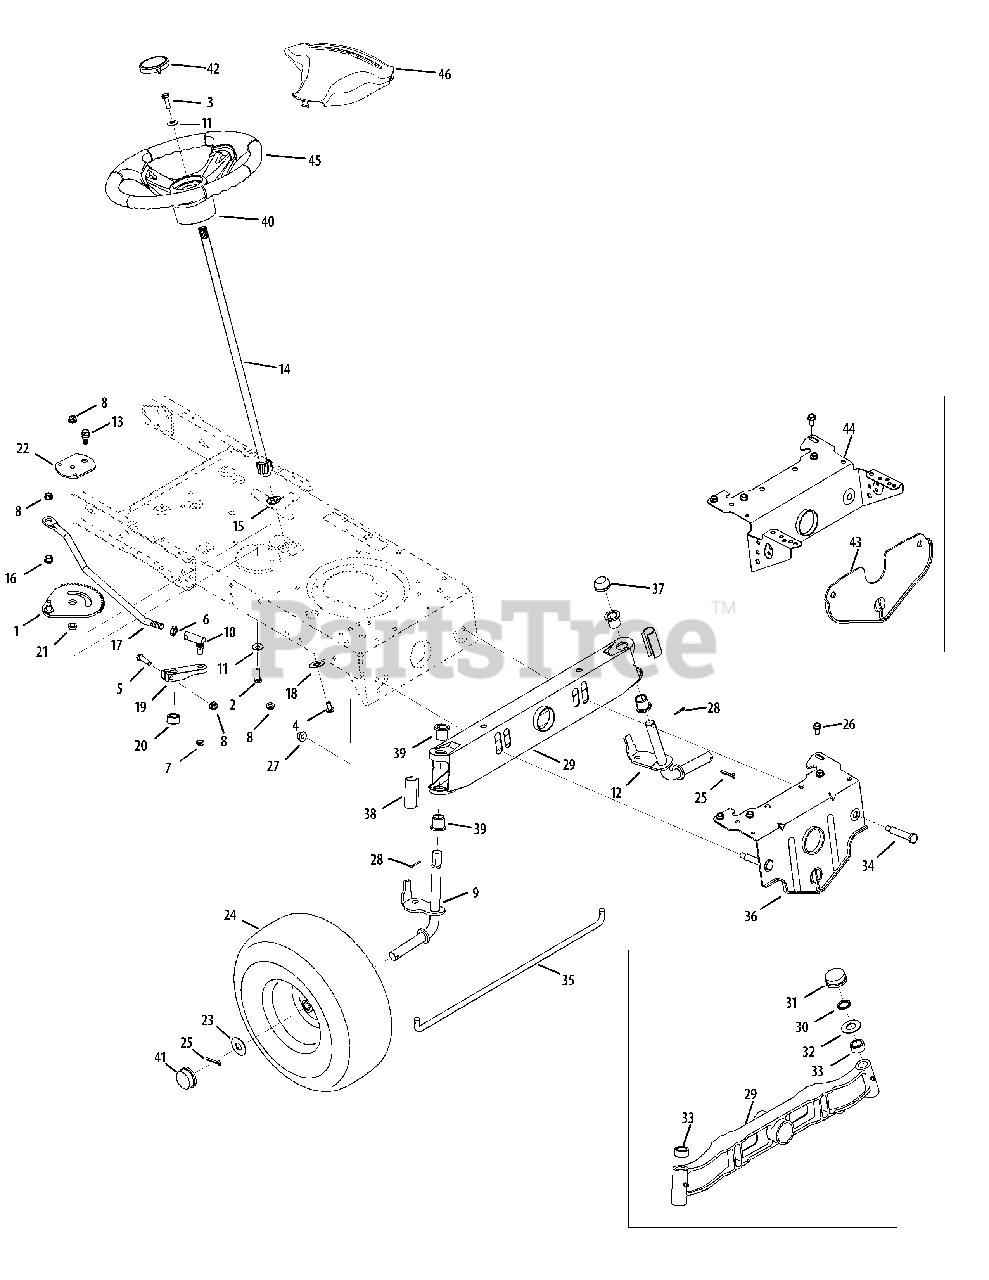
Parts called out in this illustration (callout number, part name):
1	Steering Gear Assembly
2	Hex Scr 5/16 x 1,00 Gr. 5
3	Hex Screw 5/16-18 x 1.00 Special
4	Machine Screw 5/16-18 x .75
5	Hex Screw 5/16-18 x 1.75" Lg.
6	Hex Jam Nut 7/16-20
7	Hex Cent-L Jam Nut 3/8-24
8	Flange Locknut 5/16-18 Gr. F, Nylon
9	Axle Assembly, RH
10	Ball Joint, 7/16 - 20
11	Cupped Washer .345 ID x .88 OD x .060
12	Axle Assembly, LH
12	Axle Assembly, LH (w/46" deck)
13	Shoulder Screw .435 x .3485, 5/16-18
14	Steering Shaft, 5/8 Spline x 21.86
15	Hex Flange Bearing 5/8
16	Plastic Bushing .380 ID
17	Steering Drag Link
18	Cap, 1.25 x .16
19	Steering Block
20	Spacer .710 ID x .125 OD x .56
21	Spacer .322 ID x .625 OD x .21
22	Stabilizer Plate, Gear Segment
23	Flat Washer .781 ID x 1.59 OD Special
24	Wheel Ass’y
25	Cotter Pin 5/32 x 1.25
26	S-Tapp Scr 5/16-18 x .75
27	Flange Lock-Nut 3/8-16 Gr. F, Nylon
28	Cotter Pin 1/8" Dia x .75
30	Push Nut 3/4"
32	Flat Washer .78 x 1.59 x .060
33	Spacer .71 x .125 x .56
34	Shoulder Screw .500 x 2.380, 3/8-16
36	Pivot Bar Bracket
37	Push Cap, .750
38	Axle End Cap, Standard
39	Flange Bearing .760 ID x .937 OD
40	Steering Wheel, Standard Grip
41	Plastic Hub Cap
42	Steering Wheel Cap (spig logo)
43	Front Deck Hanger Bracket
45	Steering Wheel, Soft Grip
46	Steering Wheel Cover Troy Bilt
46	Steering Wheel Cover - MTD
